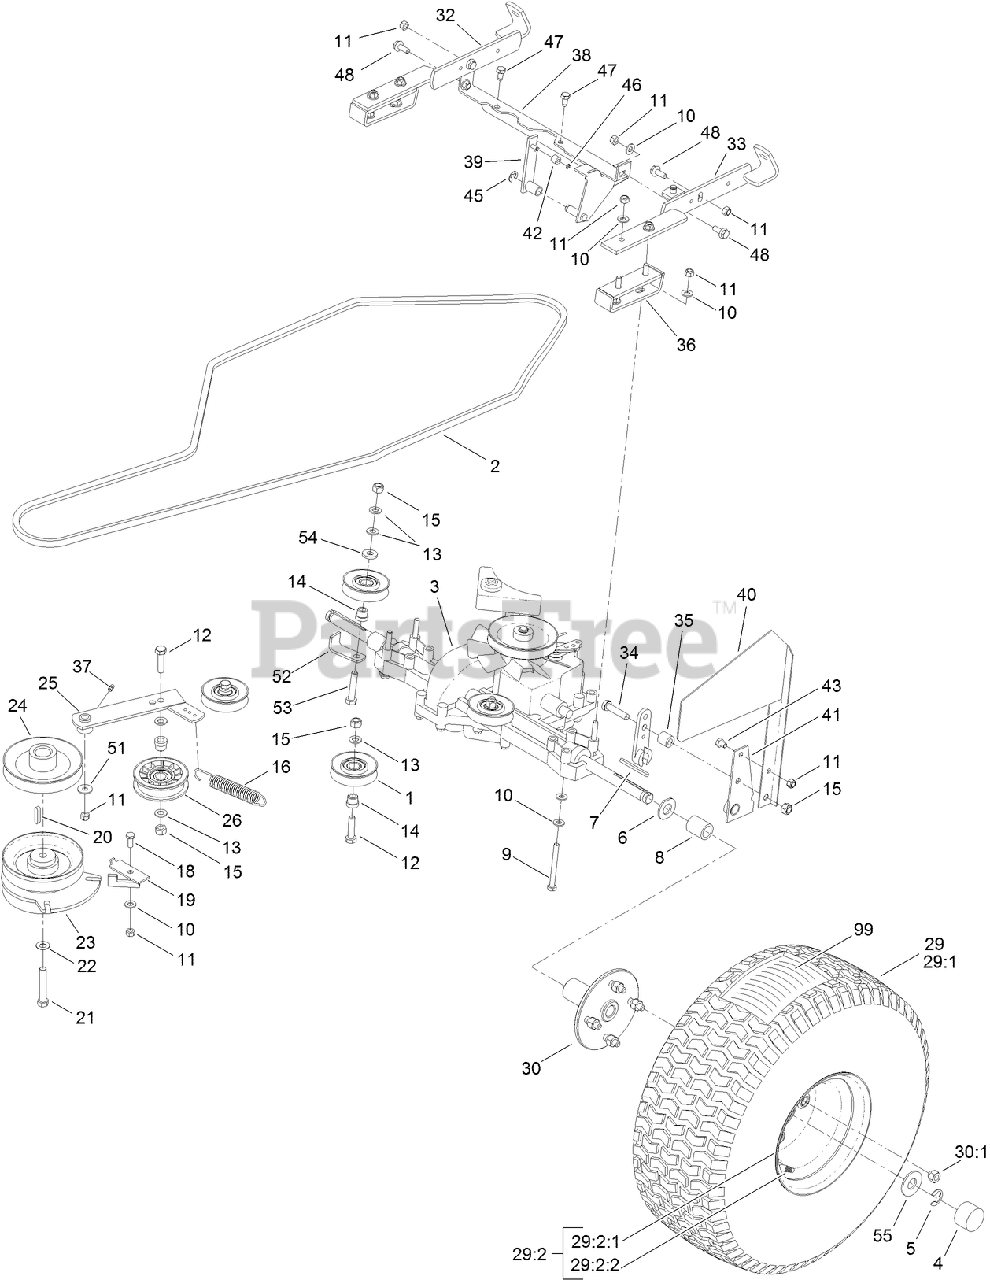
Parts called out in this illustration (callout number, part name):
1	PULLEY-IDLER
2	V-BELT-TRACTION
4	CAP-HUB
5	CLIP-SPRING
6	WASHER
7	KEY-SQUARE
8	SPACER-AXLE
9	SCREW-HH
10	WASHER-PLAIN
11	NUT-LOCK, NI
12	SCREW-HH
13	WASHER-FLAT
14	BUSHING-IDLER
15	NUT-LOCK, NI
16	SPRING
18	SCREW-HH
19	RETAINER
20	KEY-SQUARE
21	SCREW-HH
22	WASHER-SPRING, BELLEVILLE
23	CLUTCH-ELECTRIC
24	PULLEY-ENGINE
25	ARM-IDLER
26	PULLEY-IDLER
29	TIRE AND WHEEL ASM
29:2	WHEEL ASM
29:2:1	Loose Parts Package
29:2:2	Valve-Tire
30	HUB-WHEEL
30:1	NUT-LUG
32	Bracket-Right
33	Bracket-Left
34	SCREW-HH
35	SLEEVE
36	Plate-Reinforcing
37	FITTING-GREASE
38	Bar ASM
40	ARM-CONTROL, CRUISE
42	Roller
43	SCREW-HH
45	Stirrup
46	STIRRUP
47	SCREW-THREAD FORMING
48	SCREW-HEX
51	WASHER-PLAIN
52	RETAINER-BELT
53	SCREW-HH
54	WASHER-FLAT
55	WASHER
